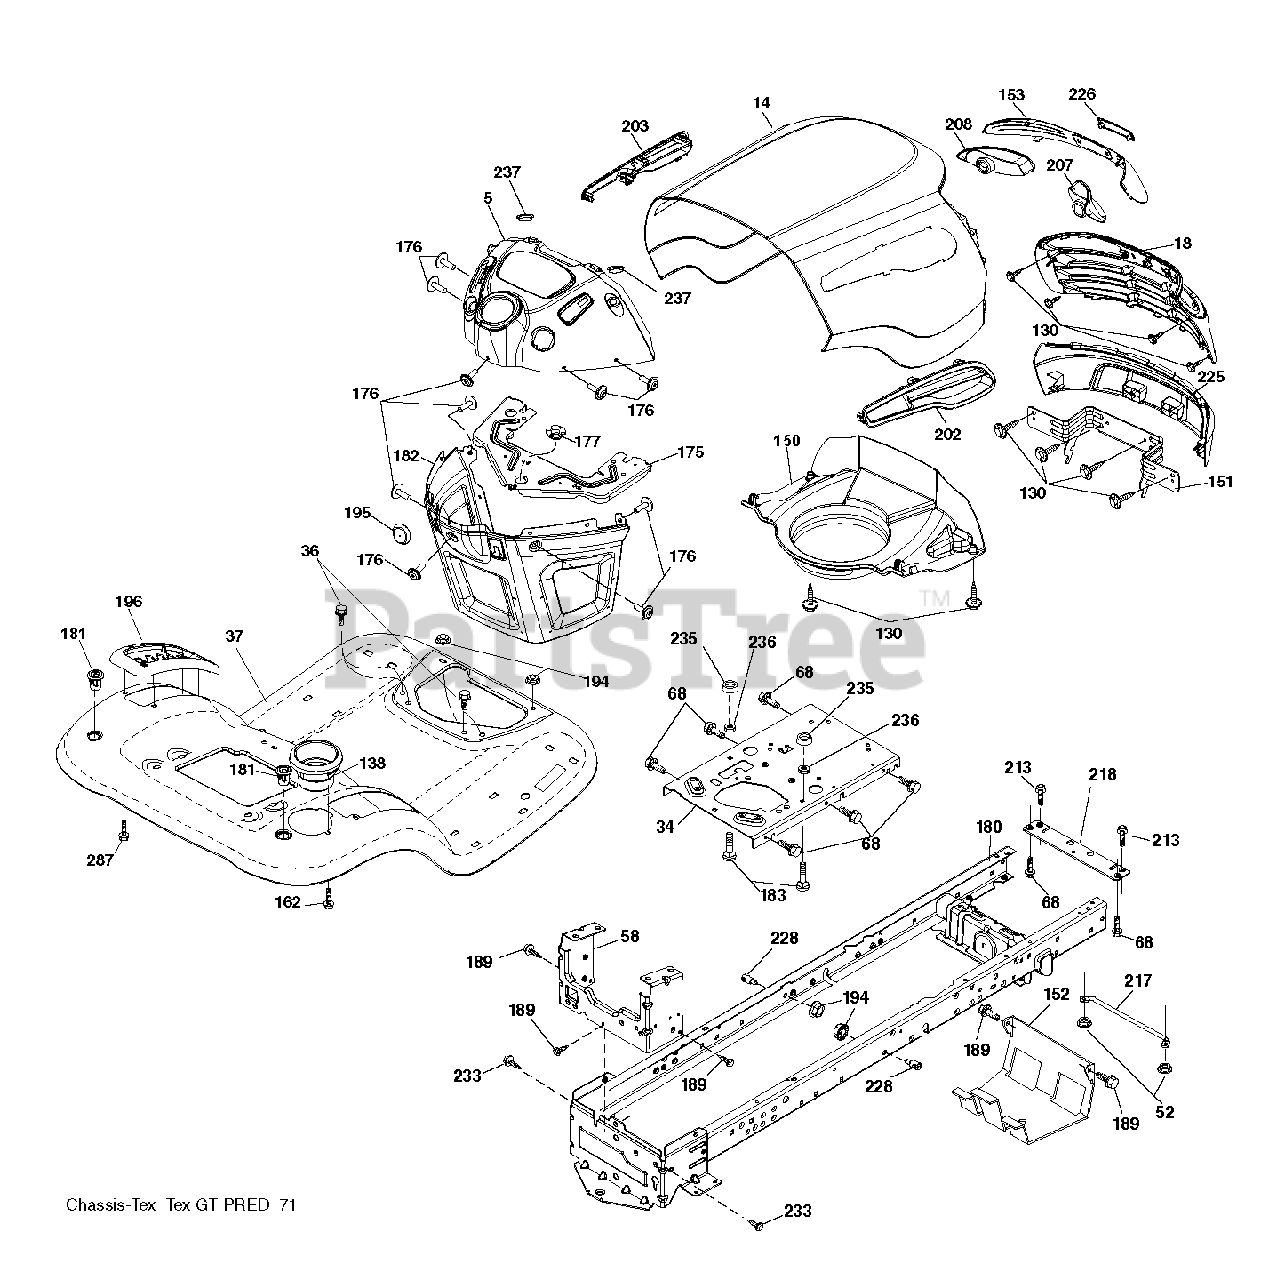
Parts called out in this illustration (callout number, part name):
5	DASH.UPPER.PRED.YT.SQ.CHOKMATC
14	HOOD.PREDATOR.YT/GT.PNT.421
18	GRILLE.SVC.PREDATOR.YT.TEX
34	PLATE.ENGINE.WELDED.CHASSIS
36	SCREW 5/16"
52	LOCKNUT
58	DRAWBAR UPPER 2PC SMALL FENDER
68	SCREW LT
130	SCREW.#10 X 0.750.BOS (2 2)
138	CUPHOLDER.TL.TEX.BLACK
150	PREDATOR.YT.GT.HOOD.AIR DUCT
151	BRACKET.PIVOT.PREDATOR
152	SHIELD.BROWNING.W/TEX
153	LOGO.PREDATOR GT.TEX.BLACK
162	SCREW.HI-LO.CONSOLE
175	PLATE.CROSSMEMBER.HUSQ
176	SCREW.#10-24X5/8.RN.QU
177	BUSHING,STEERING
180	CHASS.WLDMNT.TL.12GA/2P.48/54
181	FEND/FTRST.PCH.CPH.NFW
182	DASH.LOWER.COMMON.12V.ADAPTOR
183	BOLT.5/16-18X1-1/4 FULL THD
189	SCREW
194	NUT LOCK HEX FLANGE 5/16-18
195	PLUG.HOLE.DASH.
202	VENT. SIDE. RH.PREDAT
203	VENT. SIDE. PREDATOR
213	BOLT
217	ROD.PIVOT.HOOD
218	X-PIECE.HOOD.STOP.NON/
225	BUMPER.PREDATOR.YT.YELLOW
226	LOGO.PREDATOR GT.TEX.BLACK
228	STUD.FASTNER.W/ANTI-ROTATE
233	BOLT.SHOULDER
235	SPACER FENDER
236	NUT.CENTERLOCK.5/16-
237	PLUG.MOUNT.CARGO.BLK
287	SCREW 1/4X20
